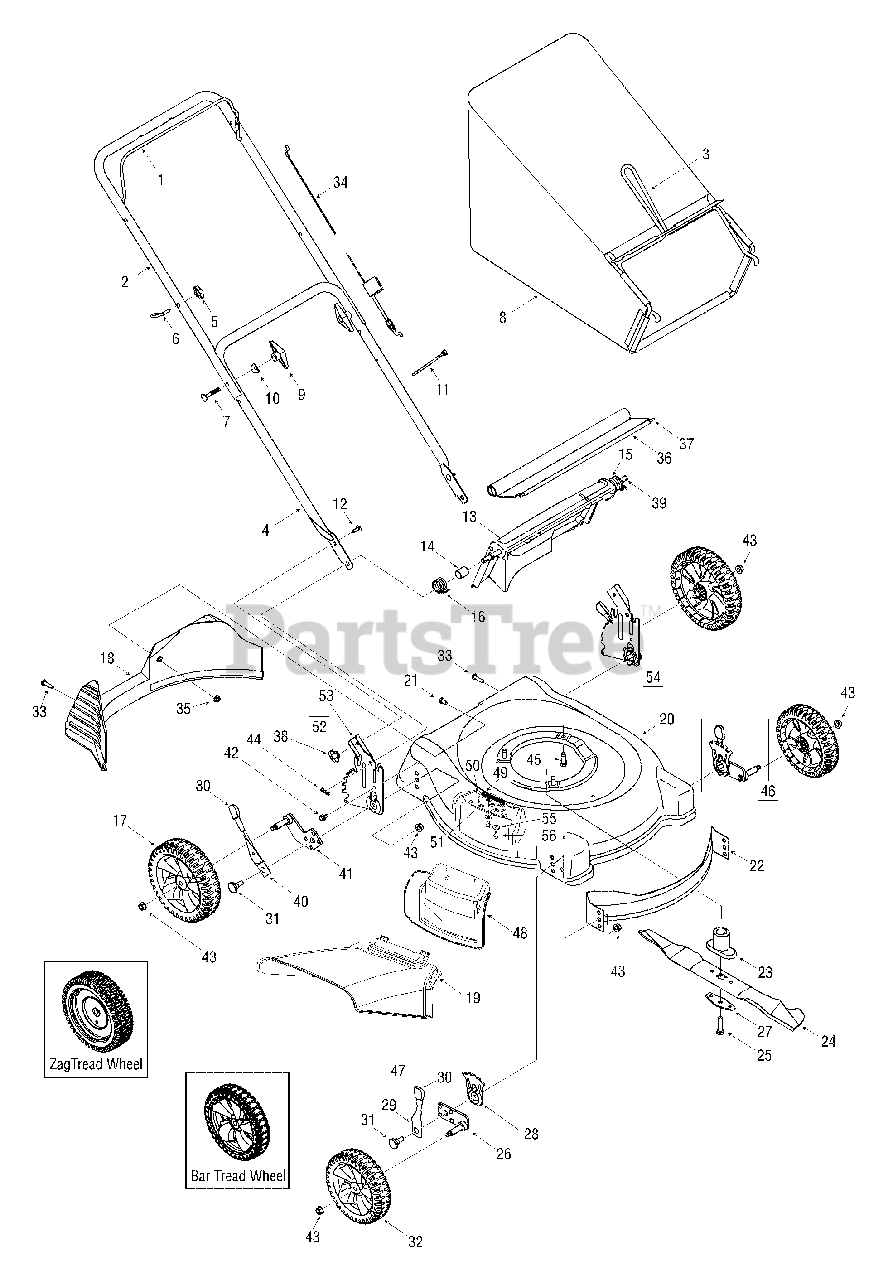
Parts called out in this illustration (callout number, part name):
5	Knob 1/4-20
6	Rope Guide Bolt
7	Curved Carriage Bolt 5/16-18 x 2.00
8	Generic Grasscatcher Bag
9	Knob 5/16-18
10	Saddle Washer
11	Cable Tie
12	Carriage Bolt 1/4-20 x .75 Gr. 1
13	RB Chute Door
14	Spacer .390 x .810 x .950
15	LH Torsion Spring
16	RH Torsion Spring
17	Wheel Ass'y 8 x 1.8 Spoke Bar Grey
18	RR Baffle
19	Side Chute Deflector
22	Front Baffle 21"
23	Blade Adapter
24	21" Blade (w/star)
25	Hex Bolt 3/8-24 x 2.5" Lg. Gr. 8
26	Pivot Bar RH
27	Blade Bell Support
28	Height Adjuster Plate
29	Spring Lever Ass'y (w/knob)
30	Knob
31	Shoulder Screw .50 Dia.
32	Wheel Ass'y 7 x 1.8 Spoke Bar Grey
33	Hex. L-Scr. 1/4-15 x 1.5
34	Control Cable 53.0" Lg. Snap-on
35	Flanged Lock Nut 1/4-20 Gr. F Nylon
36	Rear Flap
37	Wire
38	Wingnut 1/4-20
39	Pivot Rod
40	Spring Lever SP (w/knob)
41	Pivot Bar RH SP
42	Hex HD. TT Tap Scr. 1/4-20 x 5/8
43	Flange Locknut 3/8-16
44	Int. Cotter Pin 5/16 DIA
45	Hex Wash HD Tap Scr 3/8-16 x .88
47	Height Adj. Ass'y RH (w/knob)
48	Mulching Plug Ass'y
49	Torsion Spring
50	Hinge Pin
51	Plug Adapter
52	RH Rear Height Adj. Ass'y Complete
53	RH Height Adj. Brkt.
54	LH Rear Height Adj. Ass'y Complete
55	Cupp. Wash. .265 ID x .75 OD x .062
56	Hex Wash SF Tapp Scr 1/4-20 x .50
